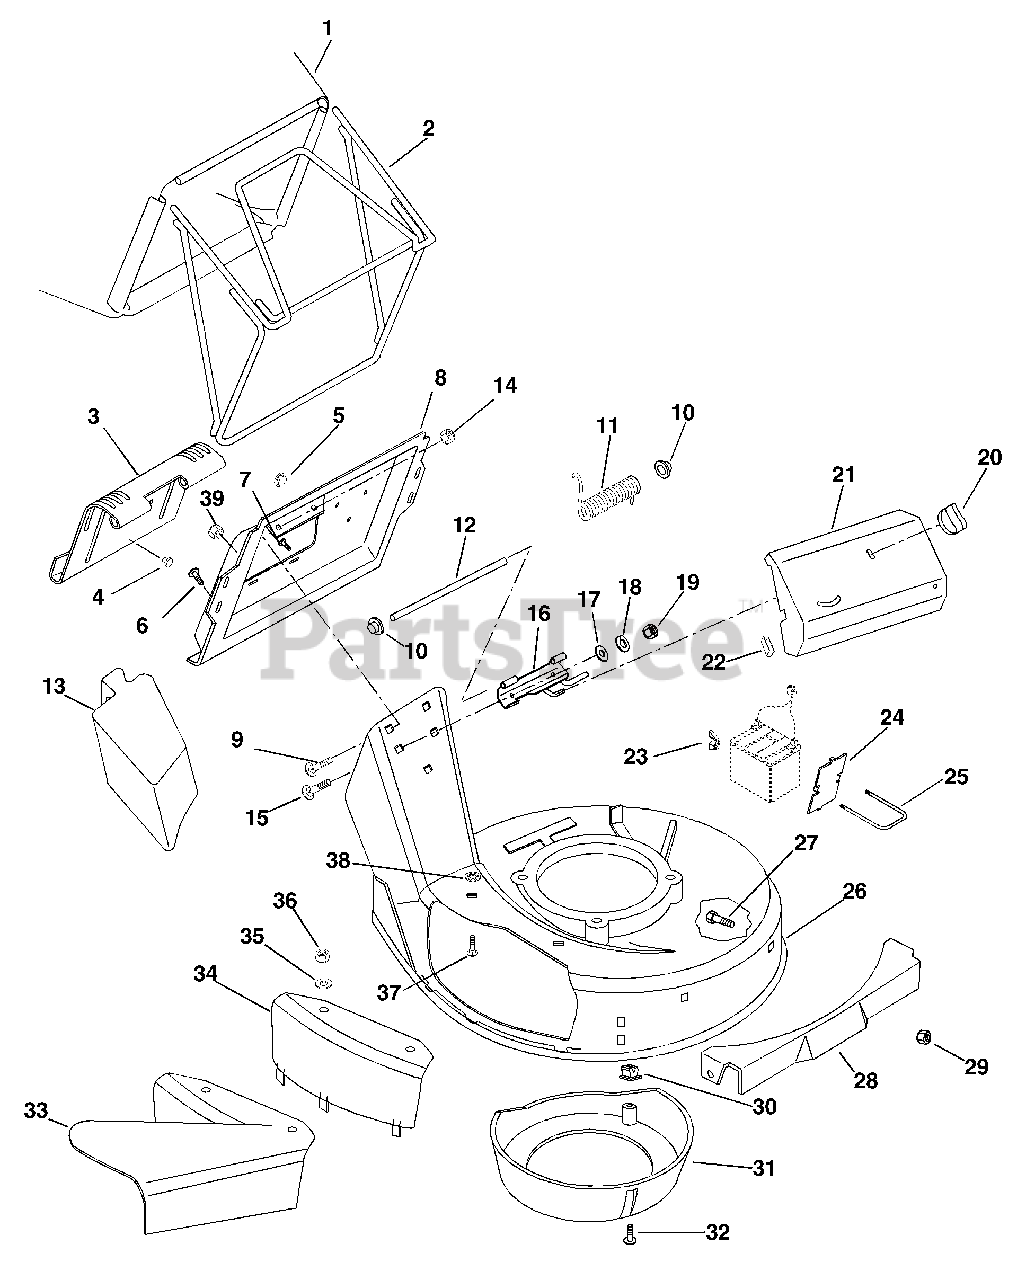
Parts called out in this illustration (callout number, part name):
1	Bag-Consumer Silver
2	Bagger Frame
3	Door-Catcher Plate
4	Button Bumper
6	Screw-Tapping 12-24 x .50 Hex Washer Head
7	Screw-Tapping 10-24 x .38 Pan Head
8	Plate-Catcher
9	Bolt-Round Head Square Neck .25-20 x .38
11	Spring-Torsion .120 x .68 x 3.09
13	Mulch Master Mulcher Accessory
14	Nut-Locking-Flange .25-20
15	Bolt-Round Head Square Neck .25-20 x .75 Grade 5
16	Hinge Base Weldment
16	Hinge Base
17	Washer-Flat-Steel .328 x .87 x .179
18	Washer-Locking .25 x .077
19	Nut-Hex .25-20
21	Drive Cover
22	Trim Bumper
23	Nut-Wing #8-32
24	Battery Plate
25	U-Bolt
26	Mower Pan Head with Decals
26	Mower Pan with Decals
27	Bolt-Round Head Square Neck .31-18 x .50 Grade 5
28	Front Panel
29	Nut-Locking-Center .31-18
30	Grommet-Plastic
31	Baffle-Center
32	Screw-Tapping 10-16 x .62 Hex Washer Head
33	Side Discharge Assembly
34	Side Discharge Cover
35	Washer-Flat-Steel .406 x .812 x .065
36	Nut-Locking-Nylon .312-18
37	Bolt-Round Head Square Neck .31-18 x .75 Grade 2
38	Nut-Push .312
39	Nut-Locking-Flange .250-20
